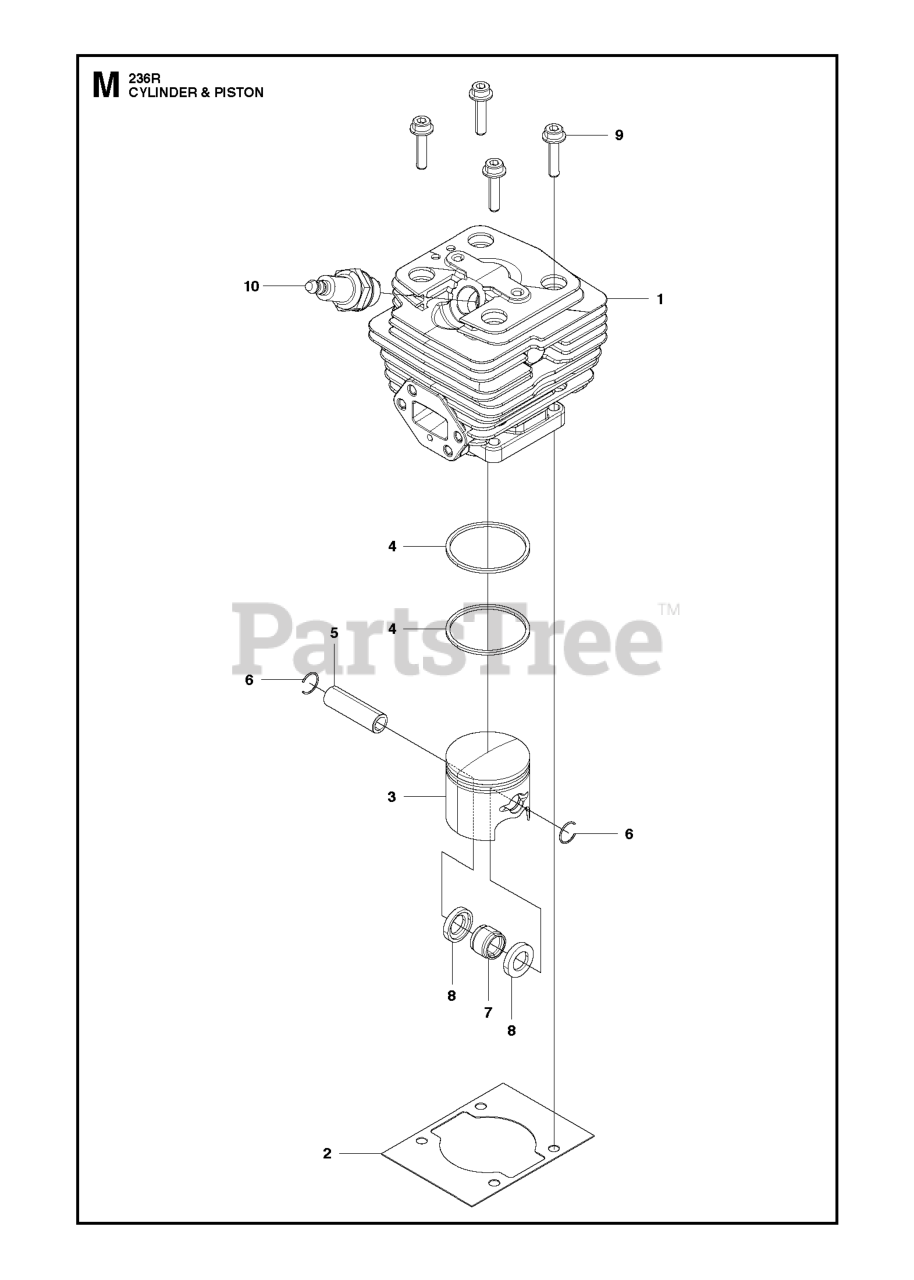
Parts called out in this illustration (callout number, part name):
1	SEAT.TH130.GRY.MILSCO.
2	BRKT.PIVOT.FENDER
3	STRAP
6	NUT
7	SPRING COMPRESSION
8	BOLT.5/16-18UNCX3/4 W/SEMS.BLK
10	PAN.ASM.SEAT.3PT
21	BOLT.SHOULDER.5/16-18
37	NUT.71038.31-18.HEX.NYLOCK
40	HANDLE.SLIDE.SEAT.TEX.BLACK
41	SPRING.LATCH.SEAT.TEX
44	WASHER 13/32 X 2-3/8 X 12GA
